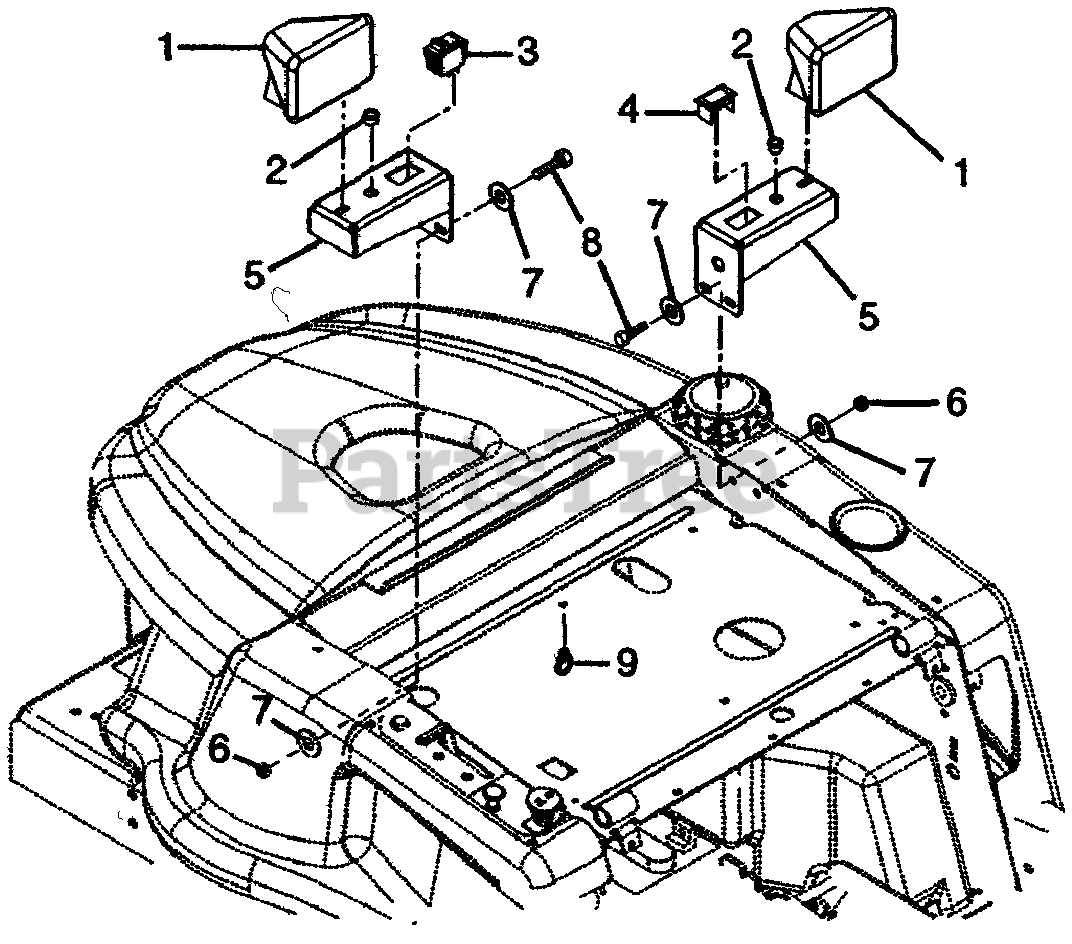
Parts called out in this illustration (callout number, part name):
1	HEADLIGHT
2	SNAP BUSHING
3	SWITCH - LIGHT
4	COVER - SWITCH
5	BRACKET, HEADLIGHT
6	@NUT-LK-NYL .312-18 YWZC
7	@WSHR-FL-STL.344X.688X.065YWZC
8	@BLT-HEX .31-18X1.00 GR5 YWZC
9	TUBE CLIP 3/4 (4158)
